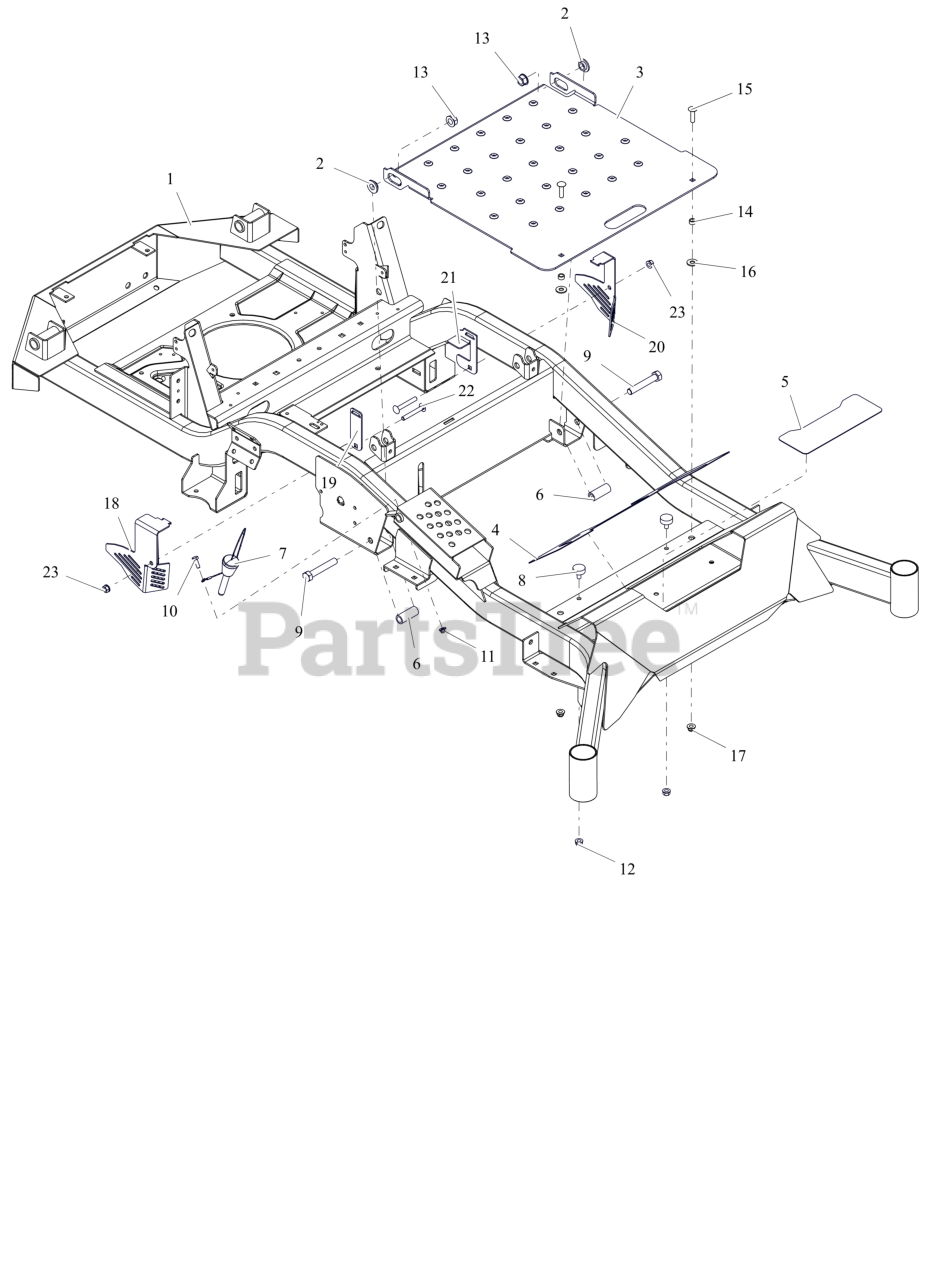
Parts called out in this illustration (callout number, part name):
1	APEX 60"FRAME W/SAFETY DECALS
2	BSHG-FLG .515X.750X.395X1.120
3	PANEL, ACCESS
4	GRIP, FRONT
5	GRIP, STEP
6	SPACER, .515X.75X1.83
7	PIN, MAGNETIC .50X2.50
8	BUMPER, RUBBER
9	BLT, HEX .50-13X3.00 G5 ZCC
10	BLT, HEX .25-20X.75 G5 ZCC
11	NUT,NYL-FLG .25-20 GF ZCC
12	NUT,SPNLK-FLG .31-18 G5 ZCC
13	NUT-LK-TOP-FLG .500-13 GF ZCC
14	BSHG-SLV .344 X .500 X .260
15	BLT, RHSSN.31-18X1.25 G5 ZCC
16	WSHR,FLT .375X.875X.083 ZCC
17	NUT,LK-NYL-FLG .31-18 G5ZC120
18	GUARD, TRANSAXLE FAN - RH
19	BRKT, TRANSAXLE FAN GUARD
20	BRKT, TRANSAXLE FAN GUARD-LH
21	MOUNT, TRANSAXLE GUARD
22	BLT, RHSSN.31-18X2.25 G5 ZCC
23	NUT,LK-CTR-FLG .31-18 GF ZCC
